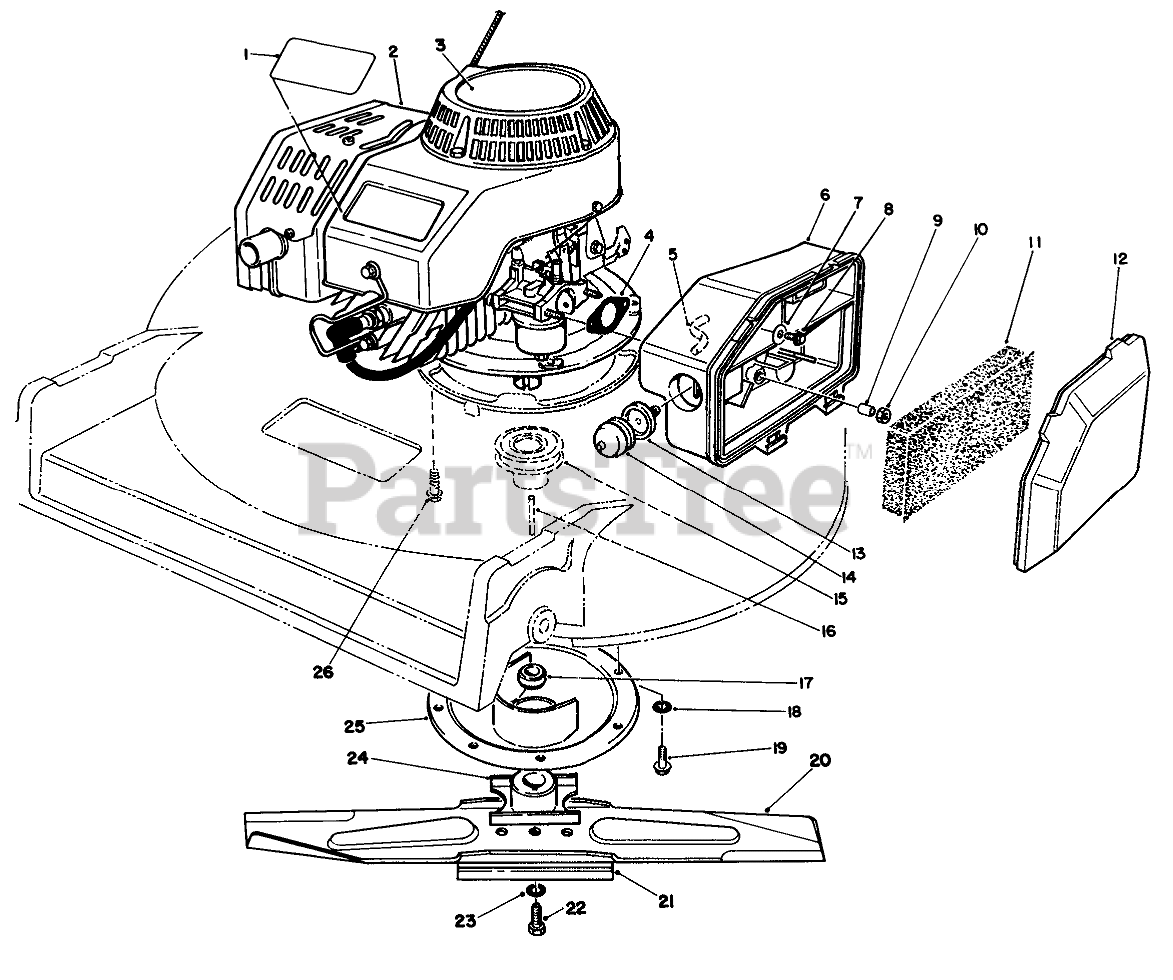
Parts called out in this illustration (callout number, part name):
1	DECAL - PROLINE
2	ENGINE ASM
3	DECAL-2 CYC RECOIL COMM
4	GASKET-AIR CLEANER
5	HOSE-PRIMER
6	BODY-AIR CLEANER
7	WASHER-FLAT
8	SCREW-HH
9	SPACER
11	ELEMENT-AIR CLEANER
12	COVER-AIR CLEANER
13	BODY-PRIMER
14	BULB-PRIMER
15	PULLEY-DRIVER
16	KEY-SQUARE
17	SPACER-BLADE RETAINER
18	WASHER-LOCK, INTERNAL
19	SCREW-HWHTF
20	Blade (Incl. Ref. #21)
21	Stiffener
22	SCREW-BLADE
23	WASHER-LOCK
24	RETAINER-BLADE
25	PROTECTOR-CRANKSHAFT
26	SCREW-HHF
